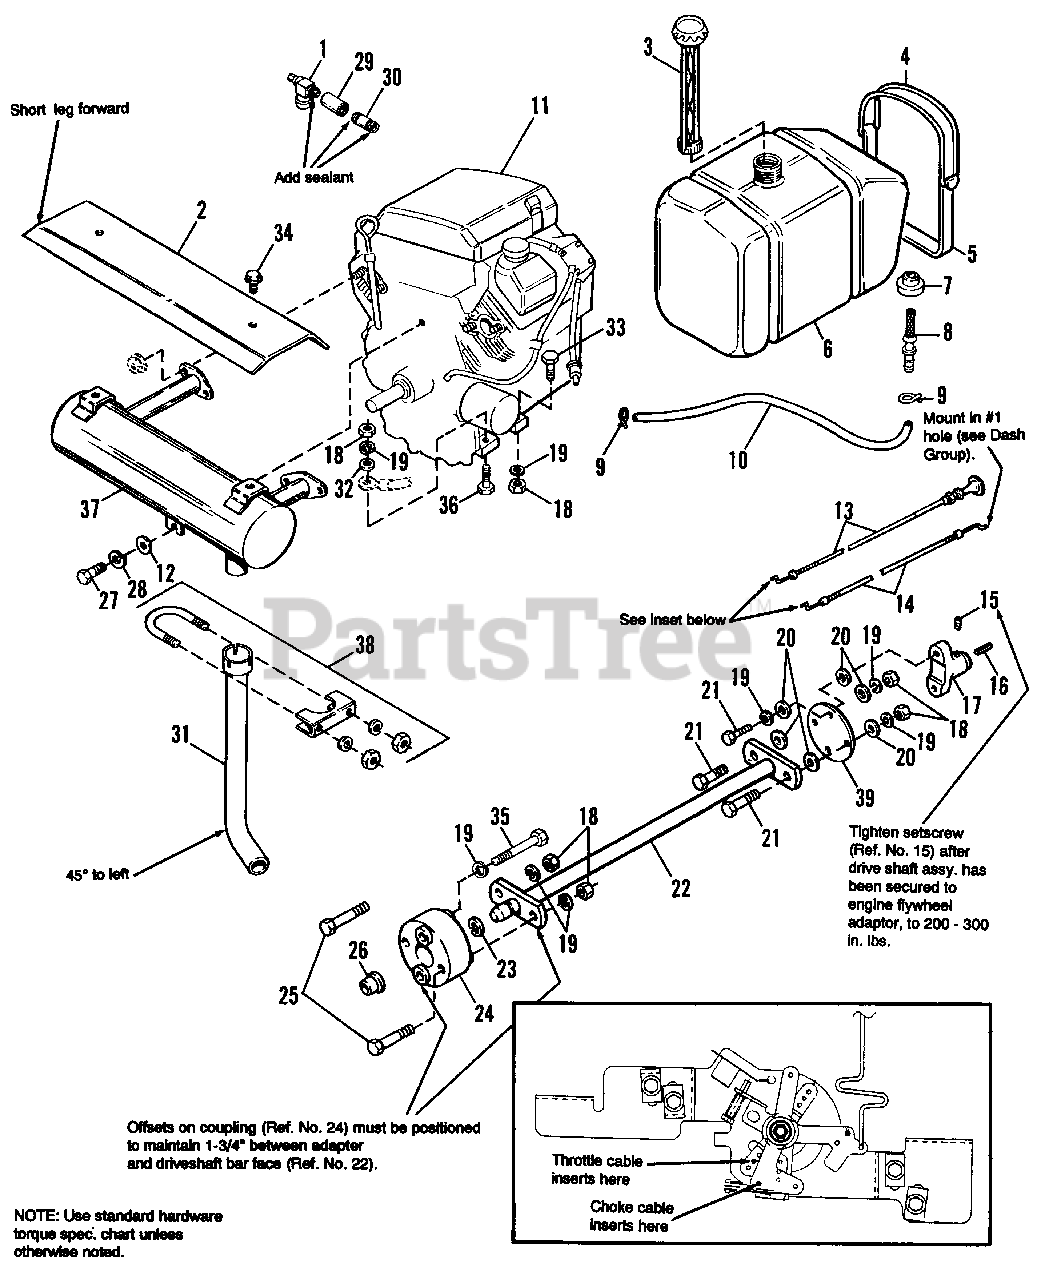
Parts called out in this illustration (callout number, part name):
1	SHUT OFF VALVE
2	HEAT SHIELD ASSY.
3	CAP, Fuel Tank
4	STRAP, Fuel Tank
5	STRAP, Tank
6	TANK ASSY., Fuel
9	CLAMP, Hose
10	HOSE, Fuel, 12"
11	ENGINE, Kohler, 18 HP
12	WASHER, 15/32
13	CHOKE CONTROL, w/knob
14	THROTTLE CONTROL
15	SETSCREW, 3/8-24 x 3/8
16	KEY, Drive Shaft
17	FLANGE, Drive Shaft
18	NUT, Hex, 3/8-16
19	LOCKWASHER, 3/8
20	WASHER, Special
21	CAPSCREW, Hex Hd., 3/8-16 x 1-1/4
22	SHAFT ASSY., Drive
23	RETAINING RING
24	COUPLING, Compression
25	CAPSCREW, Hex Hd., 3/8-16 x 2-3/4
27	CAPSCREW, Hex Hd., 7/16-14 x 1
28	LOCKWASHER, 7/16
29	COUPLING, Pipe, Straight
30	NIPPLE, Pipe, 3/8 x 1
31	PIPE, Exhaust, Elbow
32	WASHER, 11/32
33	CAPSCREW, Hex Hd., 3/8-16 x 1-1/4
34	SCREW, Hex Hd., Taptite 5/16-18 x 1/2
35	CAPSCREW, Hex Hd., 3/8-16 x 2-1/2
36	CAPSCREW, 3/8-16 x 2
37	MUFFLER, Exhaust
38	CLAMP, Exhaust
